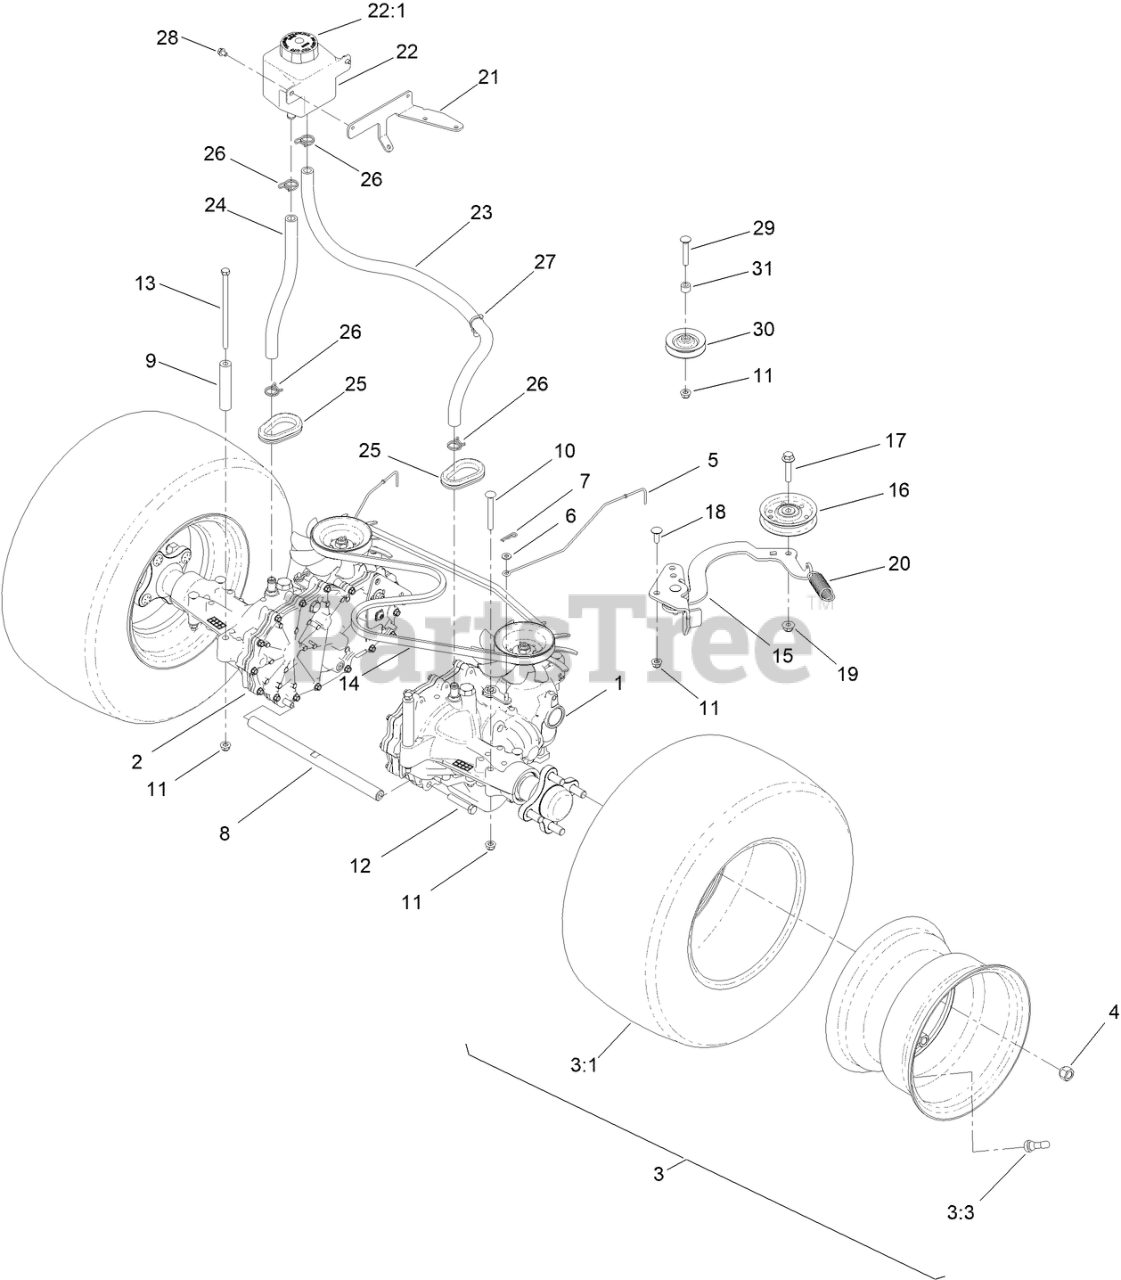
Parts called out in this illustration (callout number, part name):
1	TRANSMISSION, ZT-2800 LH
2	TRANSMISSION, ZT-2800 RH
3	TIRE ASM
4	NUT-LUG
5	ROD-BYPASS
6	WASHER-FLAT
7	PIN-COTTER
8	SHAFT-CROSS, HYDRO
9	SPACER - TRANSMISSION
10	SCREW-CARR
11	NUT-HF, NI
12	SCREW-HH W/LOCTITE
13	SCREW-HH
14	BELT-V
15	IDLER ARM ASM
16	PULLEY-IDLER, FLAT
17	SCREW-HHF
18	BOLT-CARR
19	NUT-HF, NI
20	SPRING-EXTENSION
21	BRACKET - EXPANSION TANK
22	TANK-HYD
22:1	CAP-RESERVOIR, HYD
23	HOSE-HYDRO
24	HOSE-OVERFLOW
25	GROMMET
26	CLAMP-HOSE
27	CLIP-TIE
28	SCREW-HWH
29	BOLT-CARR
30	PULLEY-IDLER
31	SPACER
